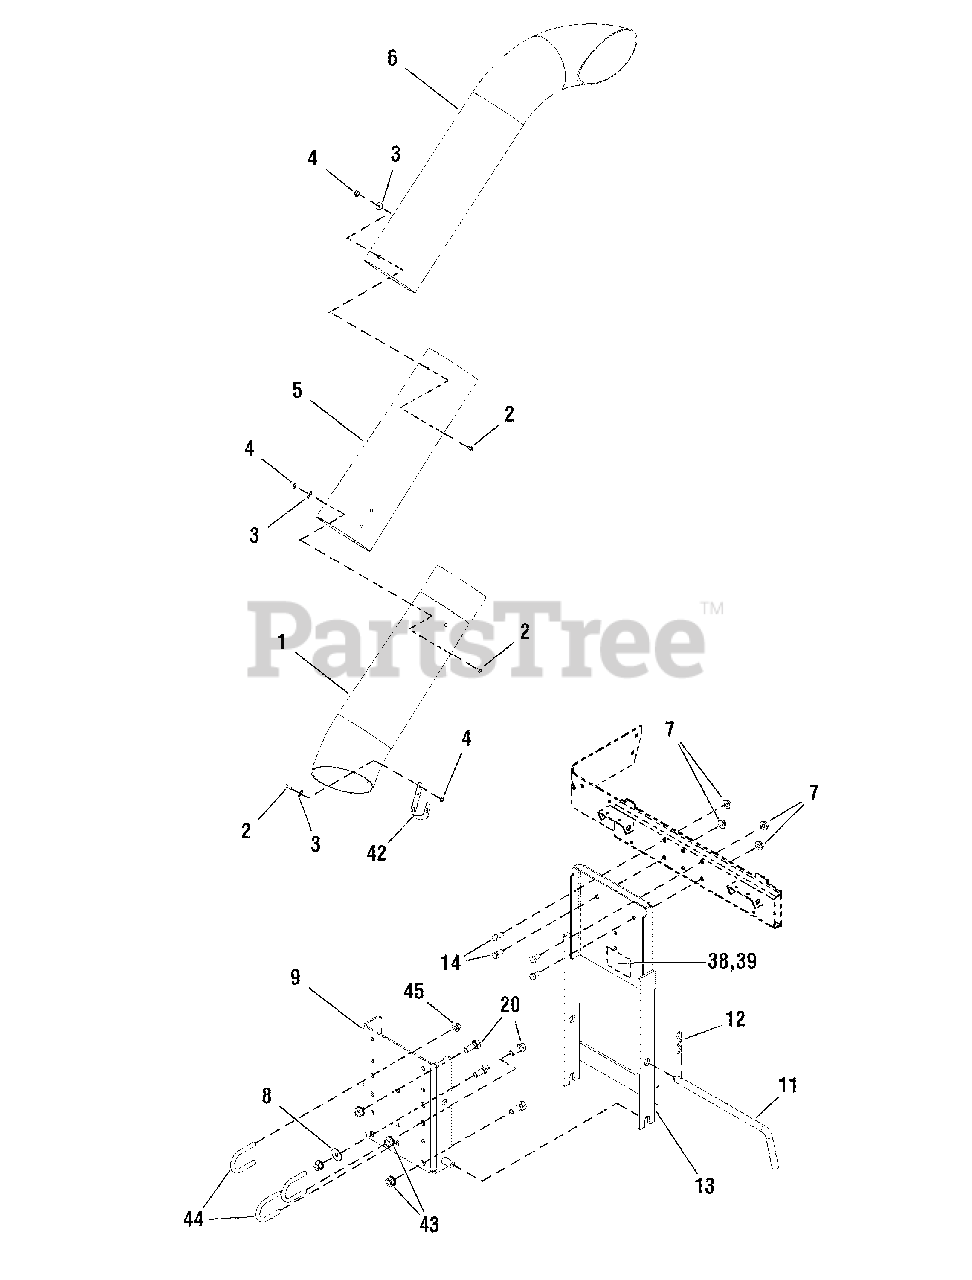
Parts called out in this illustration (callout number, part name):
2	SCREW, Truss Head, #10 - 24 x 3/4
4	NUT, Hex Nylock, #10 - 24
5	TUBE, Mid-Section
6	TUBE, Upper Section
7	NUT, Whiz Lock, 3/8 - 16
8	WASHER, 1/2
9	MOUNTING PLATE, Bumper
11	ROD, Support
12	CLIP, Hairpin
13	COVER SUPPORT ASSEMBLY
14	CAPSCREW, 3/8 - 16 x 3/4
20	CAPSCREW, Hex Head, 1/2 - 13 x 1-1/4
38	DECAL, I.D.
39	OVERLAY, Mylar
42	CLIP, Spring
43	NUT, Hex Whiz Lock Flange, 1/2 - 13
44	U-BOLT, 3/8 x 1-1/4
45	NUT, Hex Flange, 3/8 - 16, ESNA
46	OPERATORS MANUAL
